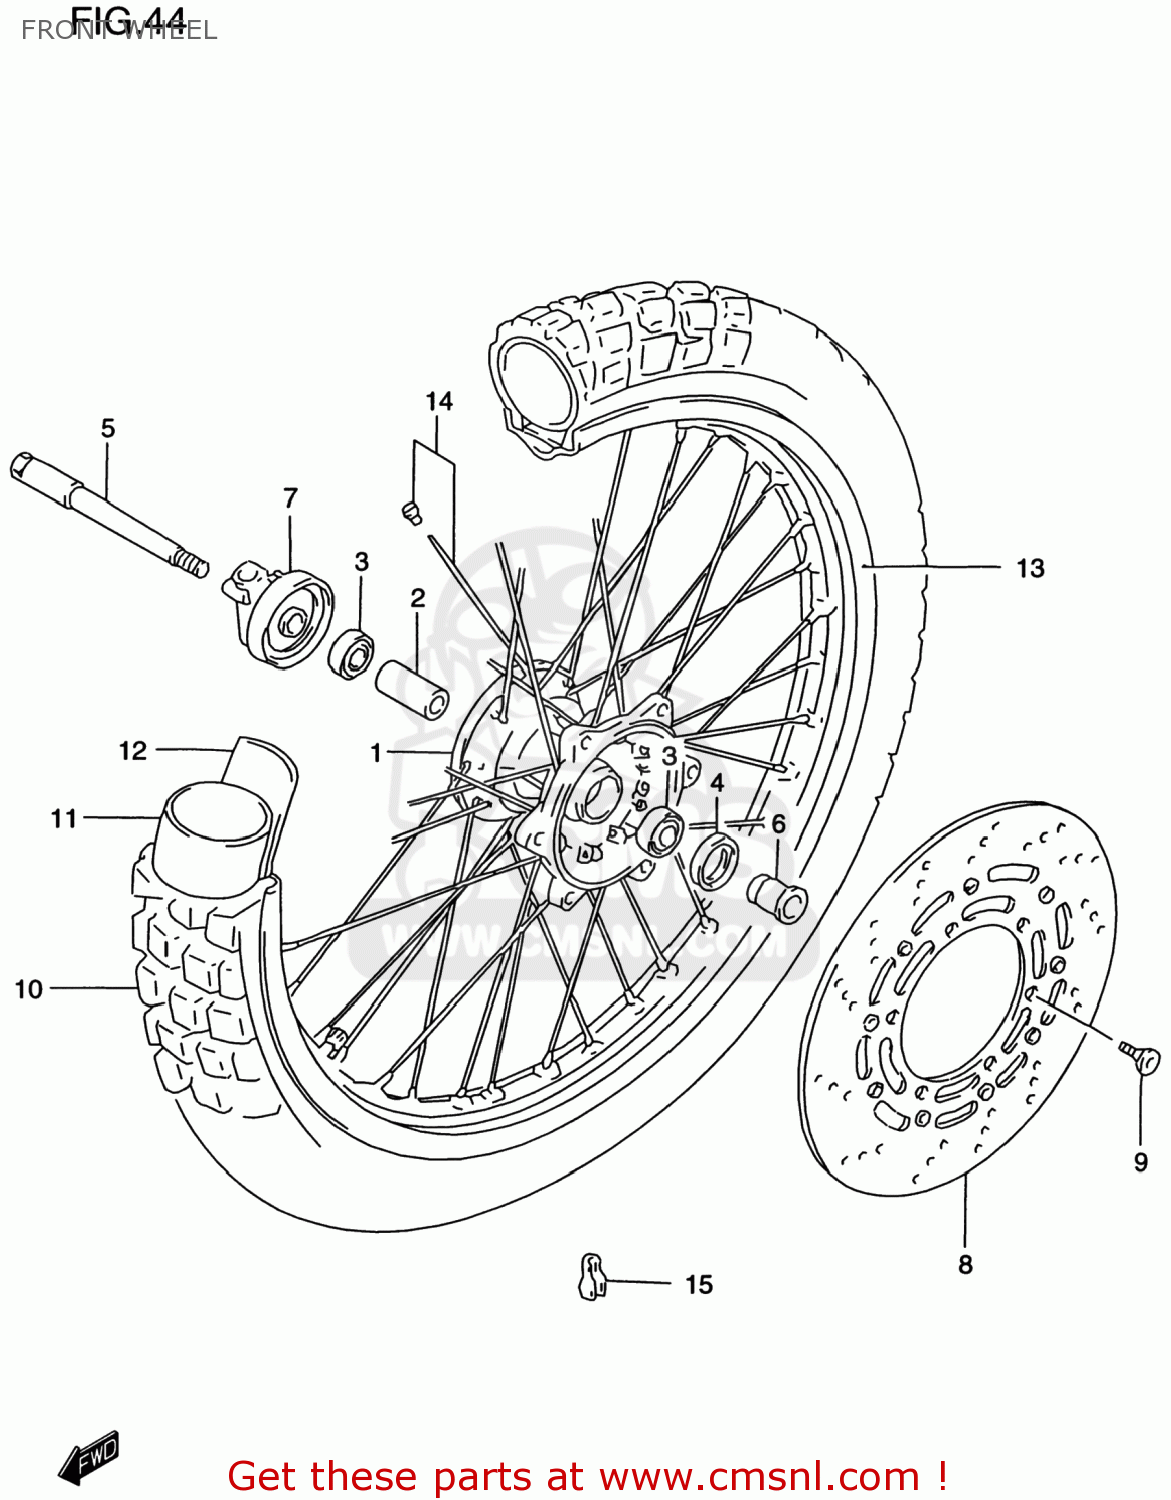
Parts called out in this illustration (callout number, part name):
1	HUB,FR WHEEL
2	SPACER,FR HUB BEARING
3	BEARING
4	SEAL,OIL(23X35X6)
5	AXLE,FR
6	SPACER,FR AXLE,L
7	BOX ASSY,SPEEDOMETER GEAR
8	DISC,FR BRAKE
9	BOLT,BRAKE DISC
10	TIRE,FR(90/90-21 54S)
11	TUBE ASSEMBLY,WHEEL,INNER
12	PROTECTOR,WHEEL,INNER
13	RIM,FR WHEEL(21X1.85)
14	SPOKE SET,FR WHEEL
15	BALANCER,WHEEL
